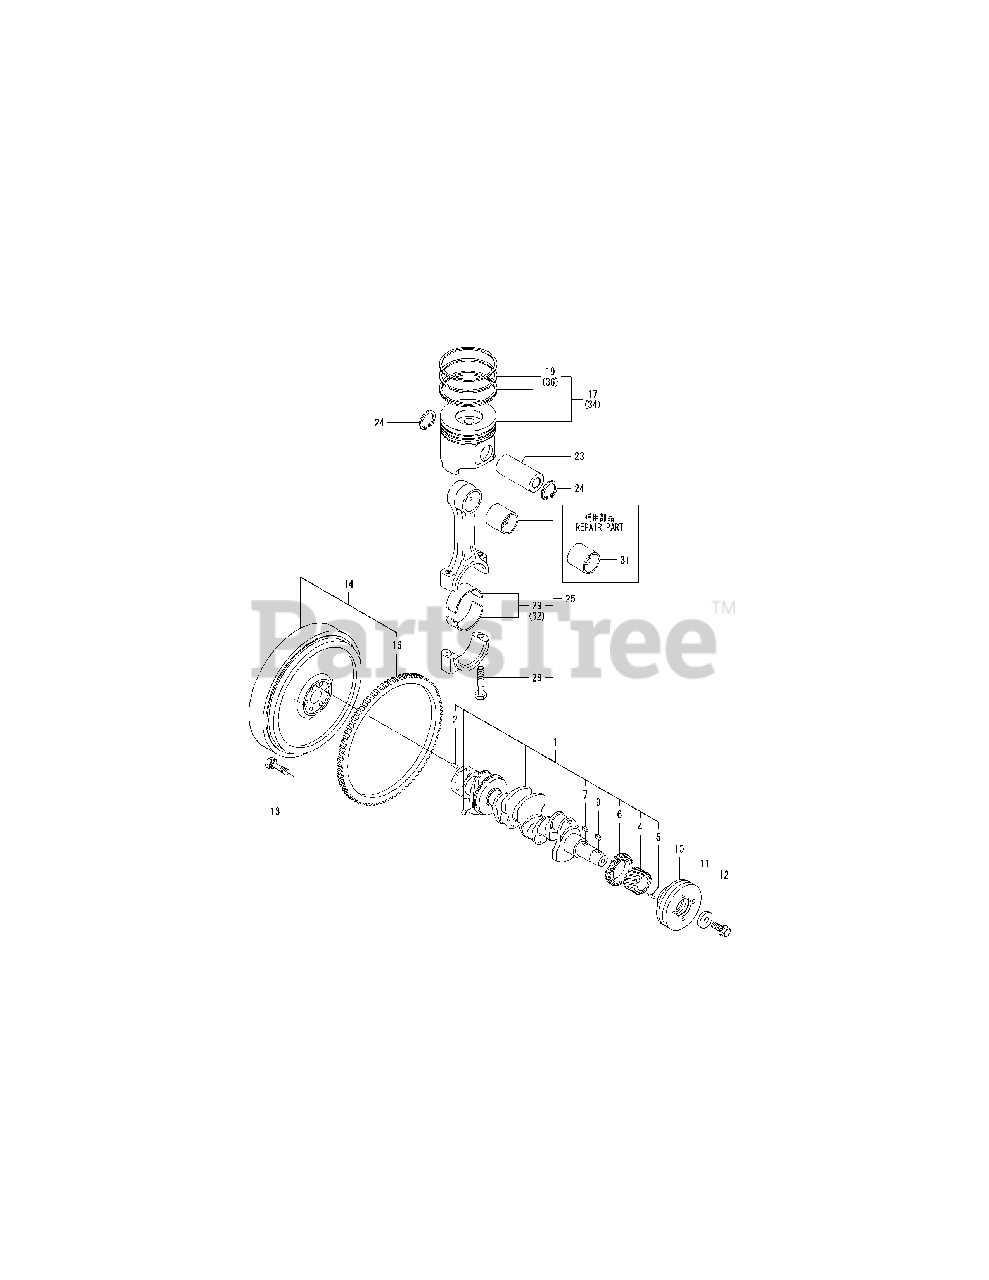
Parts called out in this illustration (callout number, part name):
1	CRANKSHAFT ASSY
4	GEAR, CRANKSHAFT
6	GEAR, BALANCER
10	V-PULLEY, CRANKSHAFT
12	BOLT, V-PULLEY
13	BOLT, FLYWHEEL
19	RING SET, PISTON
23	PIN, PISTON (D26,L70)
25	ROD ASSY, CONNECTING
28	BOLT, CONNECTING ROD
29	METAL, CRANKPIN
31	METAL, PISTON PIN
32	METAL.PIN US=0.25
34	PISTON W/RING .25OS
36	RING SET, PISTON .25
